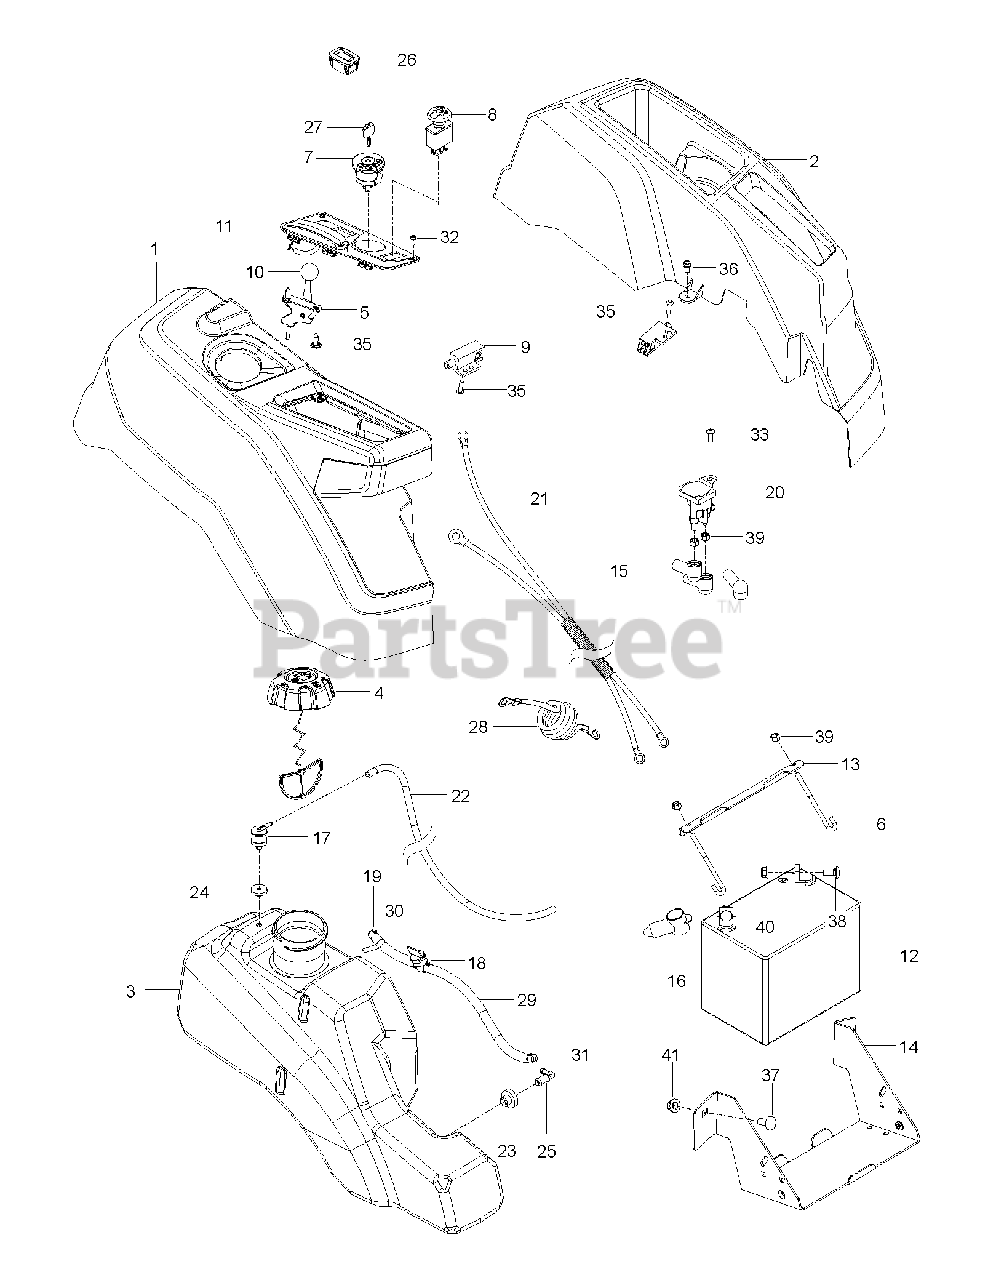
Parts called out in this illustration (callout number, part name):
1	CONSOLE.ASSY.RZ.REFRESH.RH
2	CONSOLE.LH.ASM
3	TANK.ASM3"NECK.NOCAP.NOSHDRZ17
4	CAP ASSY FUEL 3" GRAY
5	CABLE.THROTTLE.37"
6	HOOK.J.BATTERY
7	RP IGNITION SWITCH
8	RP SWITCH.PTO.TERMINAL.STD.RED
9	SWITCH.INTLK.RZ.RFRSH.BUTTON
10	KNOB.ROUND.BALL.BLACK
11	CONTROL.PANEL.RZ.REFRESH.RH
12	BATTERY, 12 V 330 AMP
13	BRACKET.PNT.MOUNT.BATTERY.EDIP
14	BOX.PNT.BATTERY.RZ.EDIP
15	TERMINAL COVER
17	VALVE.FUEL.CHECK
18	FUEL VALVE
19	FUEL.HOSE.SHUT.OFF.ASM.10".3"
20	SOLENOID.STARTER.BRASS.PLUNGER
21	HARNESS.BTTRY.CABLE.RZ.REFRESH
22	HOSE.3/16".VAPOR.LINE.23"LGTH
23	BUSHING OUTLET T
24	GROMMET.ROV.SENTEC
25	STEM FUEL TANK
26	GUAGE.SRVCMNDR.HRMTR.
27	KEY MLD GEN DELTA
28	CABLE BATTERY POS RZ
29	HOSE.1/4".LOW.PERM.FUEL.LN.10"
30	HOSE.1/4".LOW.PERM.FUEL.LN.3"
31	HOSE CLAMP
32	SCREW 6-19X.437
33	SCR 1/4-20 X 5/8 BTN SKT HD ZD
34	SCREW.PAN.HEAD.#10
35	SCREW.BUTTONHD.10-24X1/2.(2 2)
36	SCREW
37	RHSNB 3/8C X 1
38	BOLT 5/16-18 X3/4 ZN/YEL GR 5
39	RP_NUT 1/4-20 NYLOC
40	5/16-18 NYLOC FLANGE NUT
41	NUT 3/8-16 HEX FLG NYLOC ZD
